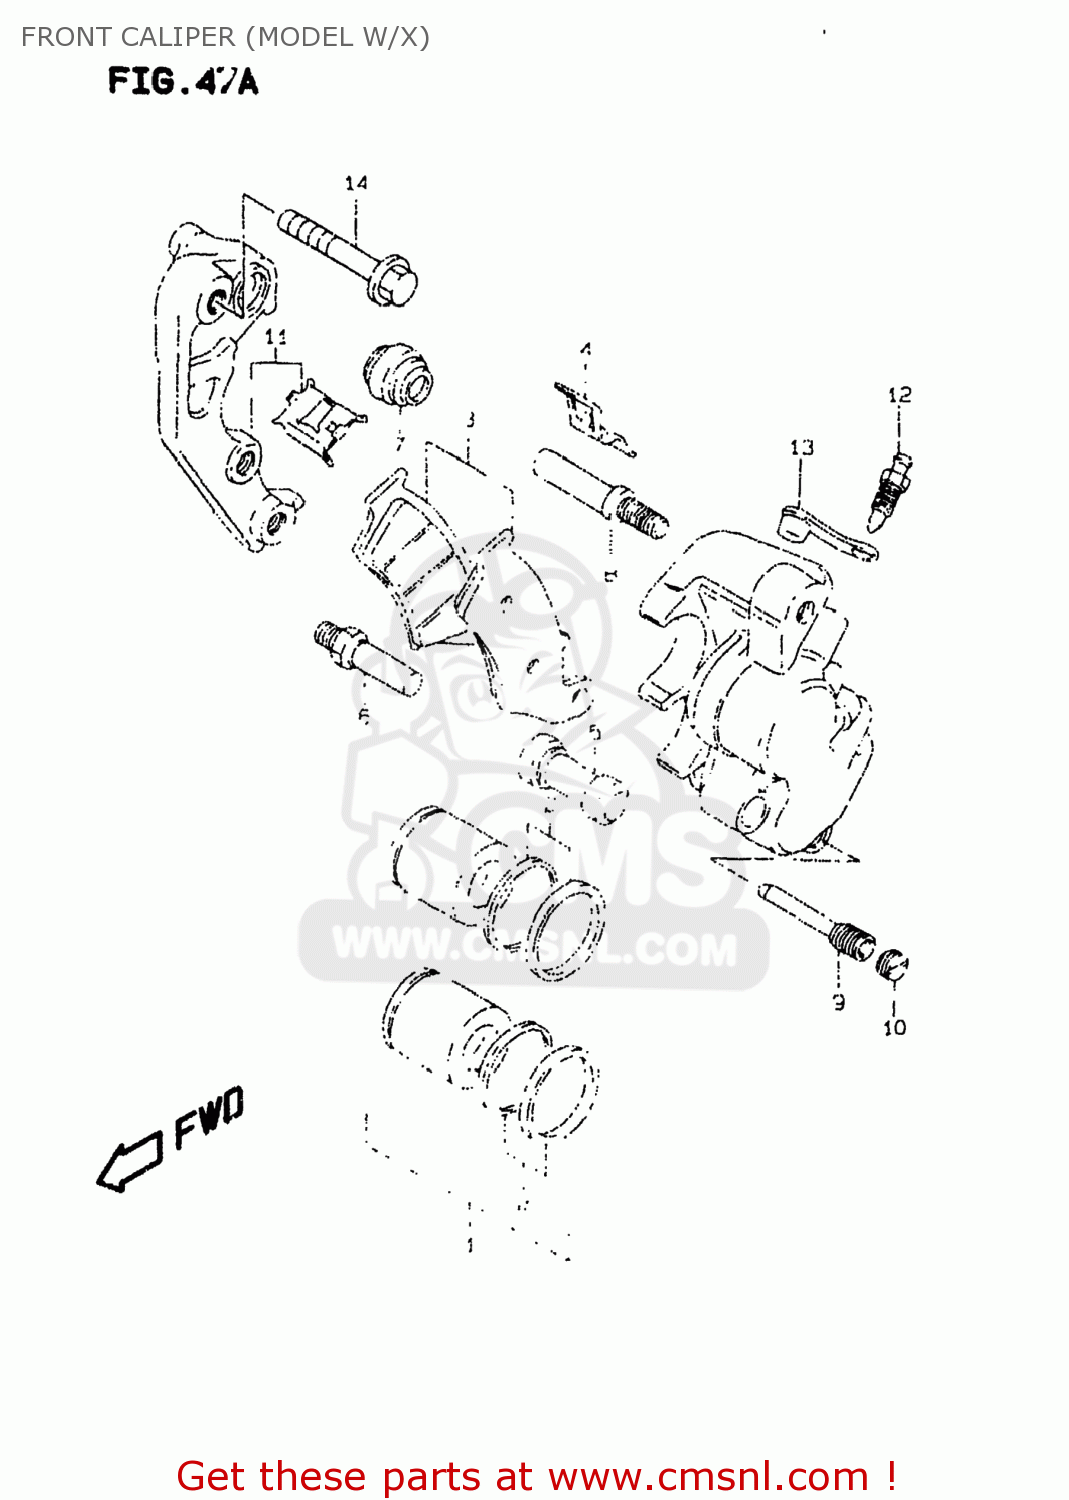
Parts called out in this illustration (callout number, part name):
1	PISTON SET
2	SEAL SET,PISTON
3	PAD SET (NAS)
4	SPRING,PAD
5	BOOT
6	BOLT
7	BOOT
8	PIN
9	PIN,HANGER
10	PLUG,PIN
11	BRACKET
12	BLEEDER
13	CAP,BLEEDER
14	BOLT(8X40)
